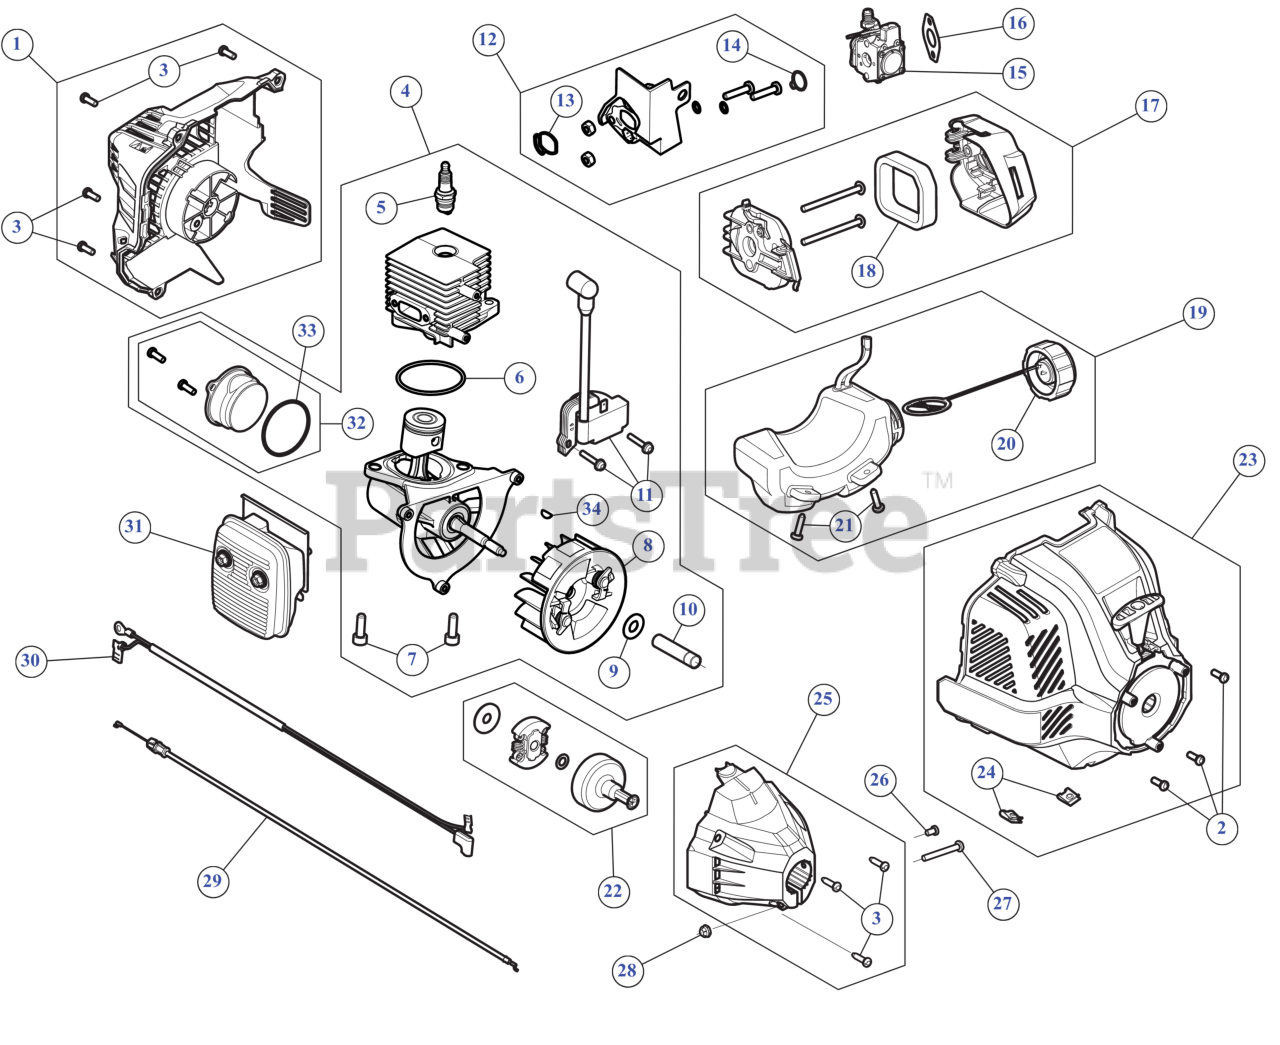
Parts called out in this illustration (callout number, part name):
1	REAR ENGINE COVER
2	SCREW #10-24X11/16 T-25
3	SCREW 8-16 x 3/4
4	SHORT BLOCK 25cc
5	SPARK PLUG
6	O-RING SEAL CYLINDER
7	SCREW 5/16-18x3/4 T40
8	FLYWHEEL ASSEMBLY
9	BELL WASHER
10	SPACER :2.165"
11	MODULE
12	INTAKE ASSEMBLY
13	INSL/CYL SEAL
14	CARBURETOR SEAL
15	CARBURETOR
16	GASKET CARB
17	AIR CLEANER COVER
18	AIR FLITER
19	FUEL TANK ASSEMBLY
20	FUEL CAP ASSEMBLY
21	SCREW:10-6 x .75
22	SMALL CLUTCH ASSEMBLY W/SMALL DRUM
23	STARTER HOUSING (LIBERTY RED)
24	NUT, TINNERMAN U-T
25	CLUTCH COVER
26	SCREW, 8-32 x .312 P
27	SCREW 10-24 X 1.12
28	HEX NUT
29	THROTTLE CABLE
30	LEAD WIRES
31	MUFFLER
32	CRANKCASE COVER
33	O-RING SEAL CRANKCASE
34	WOODRUFF KEY #403-.125 x .375
